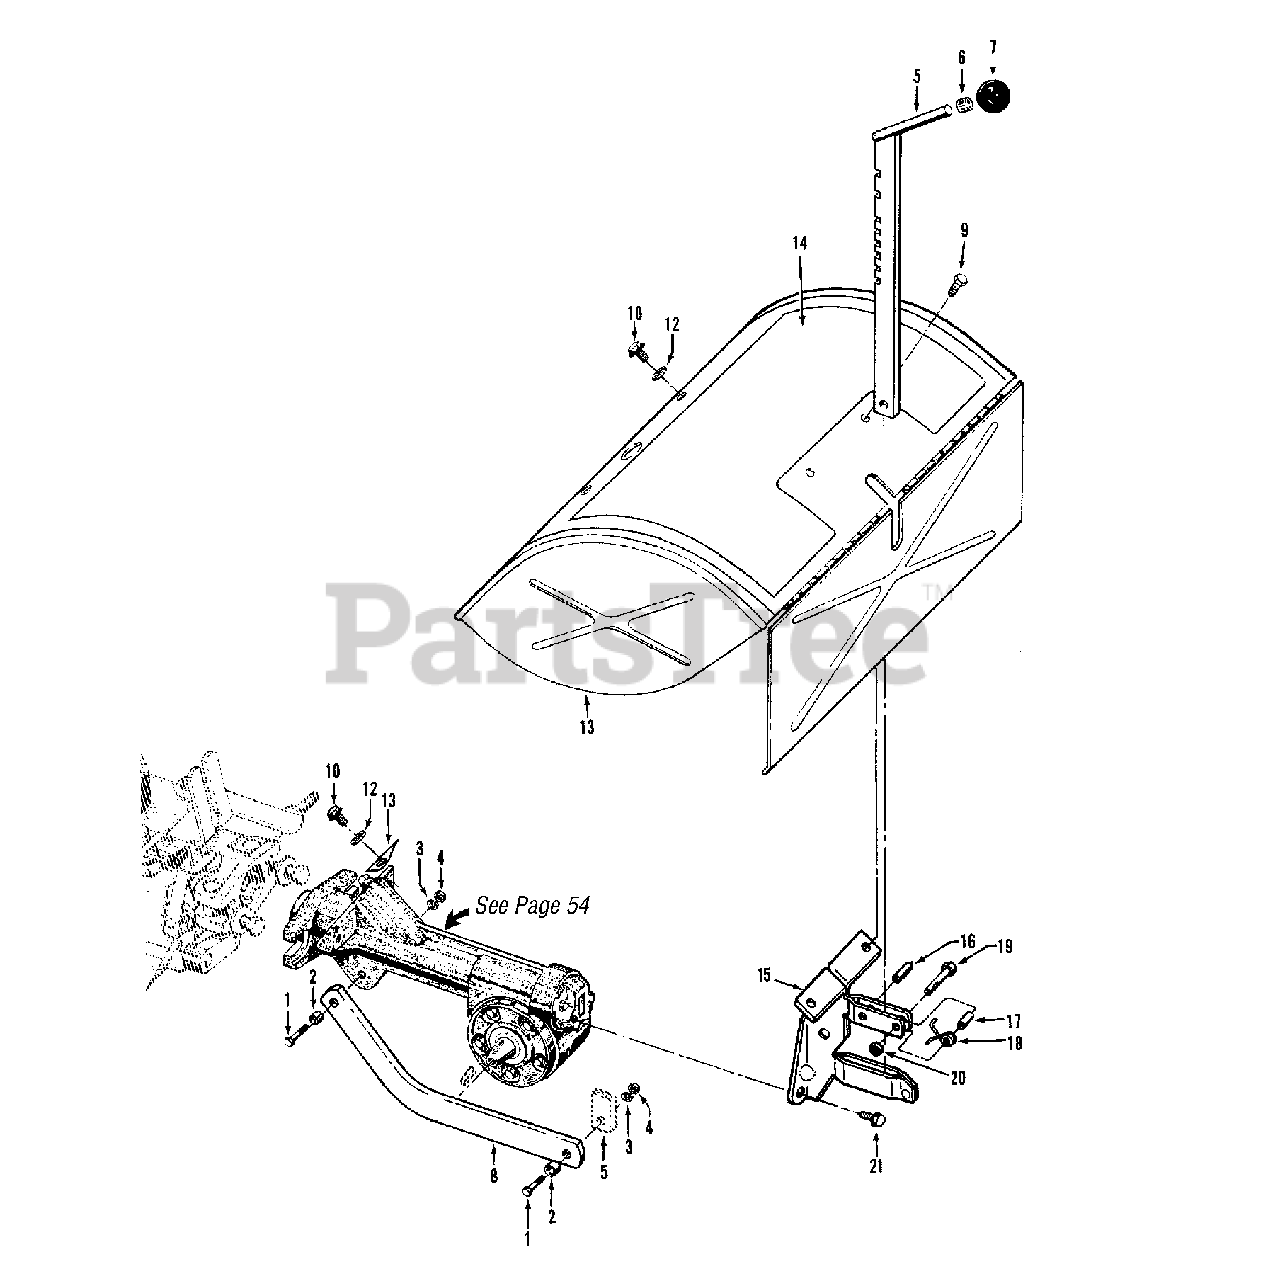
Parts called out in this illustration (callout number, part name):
1	Bolt-hex hd., 3/8-16 x 1-1/4"
2	Bushing-19/64" (.300" lg.)
3	Lockwasher-spring lock, 3/8"
4	Nut-hex, 3/8"-16
5	Bar-depth regulator
6	Ring-retaining
7	Knob-depth regulator
8	Bar-drag, depth regulator
9	Screw-thread-forming, 1/4-20 x 1/2"
10	Bolt-flanged hex hd., 5/16-18 x 3/4"
12	Washer-flat, 5/16"
14	Decal-hood, operating instructions
16	Pin-roll (spirol) 1/4" x 1"
18	Spring
19	Bolt-hex hd., 1/4-20x1"
20	Locknut-1/4"-20
21	Bolt-flanged hex hd., 5/16-18 x 5/8"
